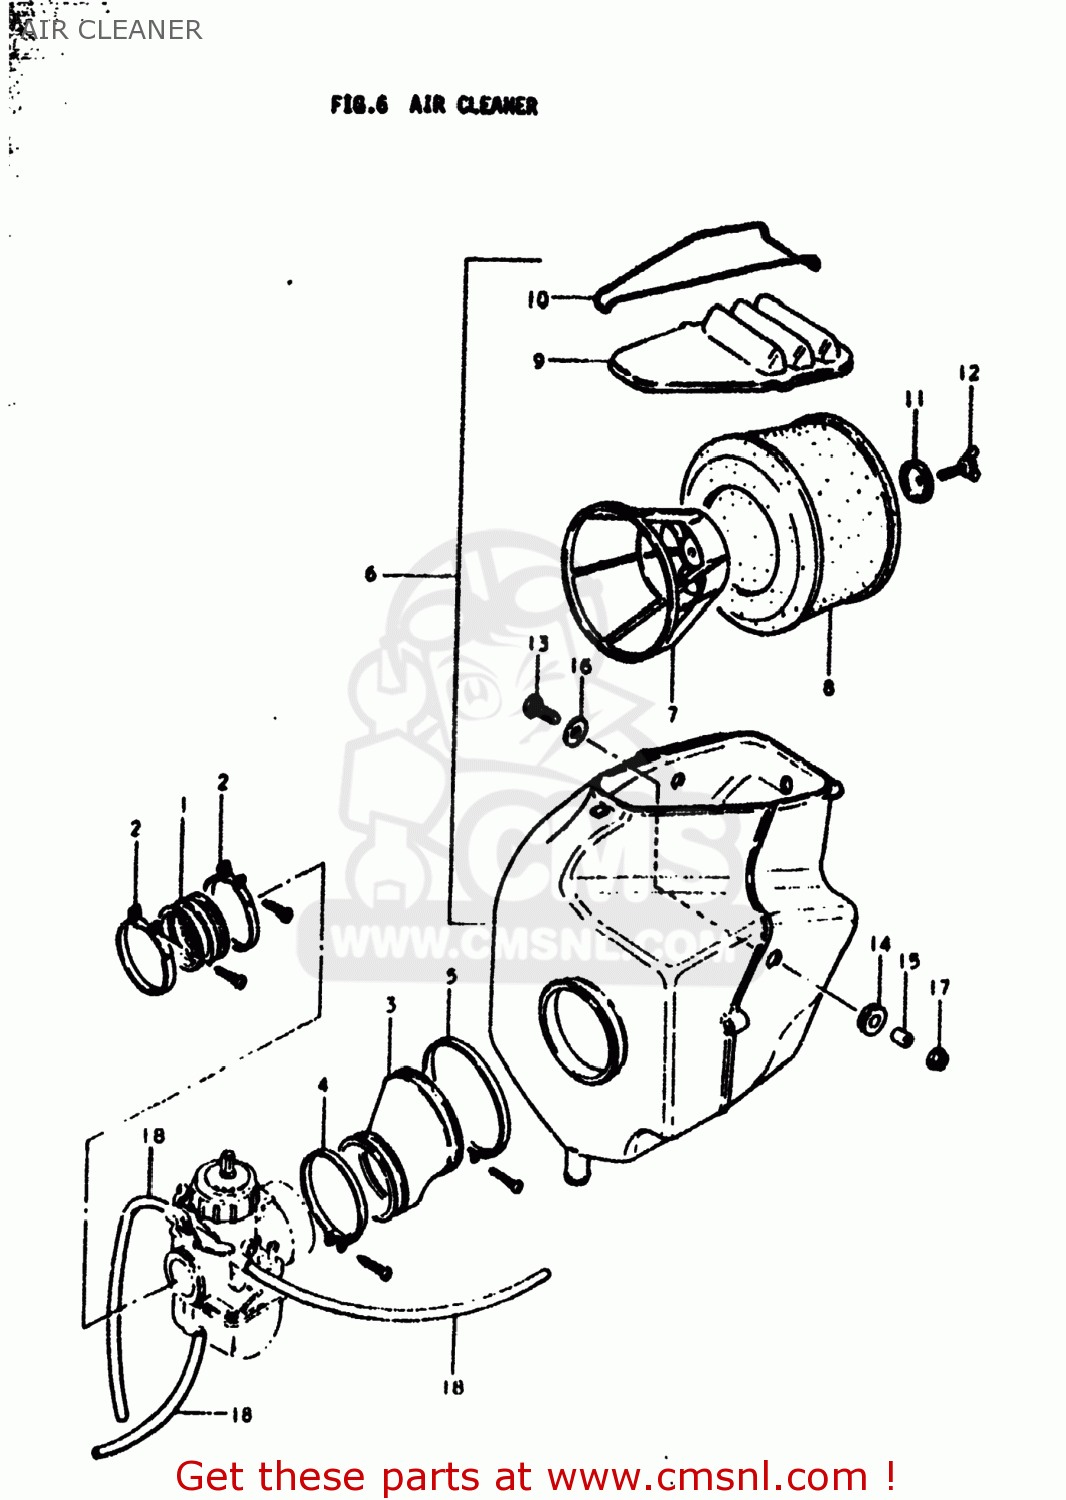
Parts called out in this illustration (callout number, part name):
1	PIPE,INTAKE
2	CLAMP
3	TUBE,AIR CLEANER OUTLET
4	CLAMP
5	CLAMP
6	CLEANER ASSEMBLY,AIR
7	HOLDER,FILTER
8	ELEMENT,AIR CLEANER
9	CAP,AIR CLEANER
10	O RING
11	HOLDER,FILTER
12	WING BOLT,AIR CLEANER
13	BOLT
14	CUSHION
15	SPACER (6.1X9X9)
16	WASHER(6.5X20X1.2)
17	NUT
18	HOSE
